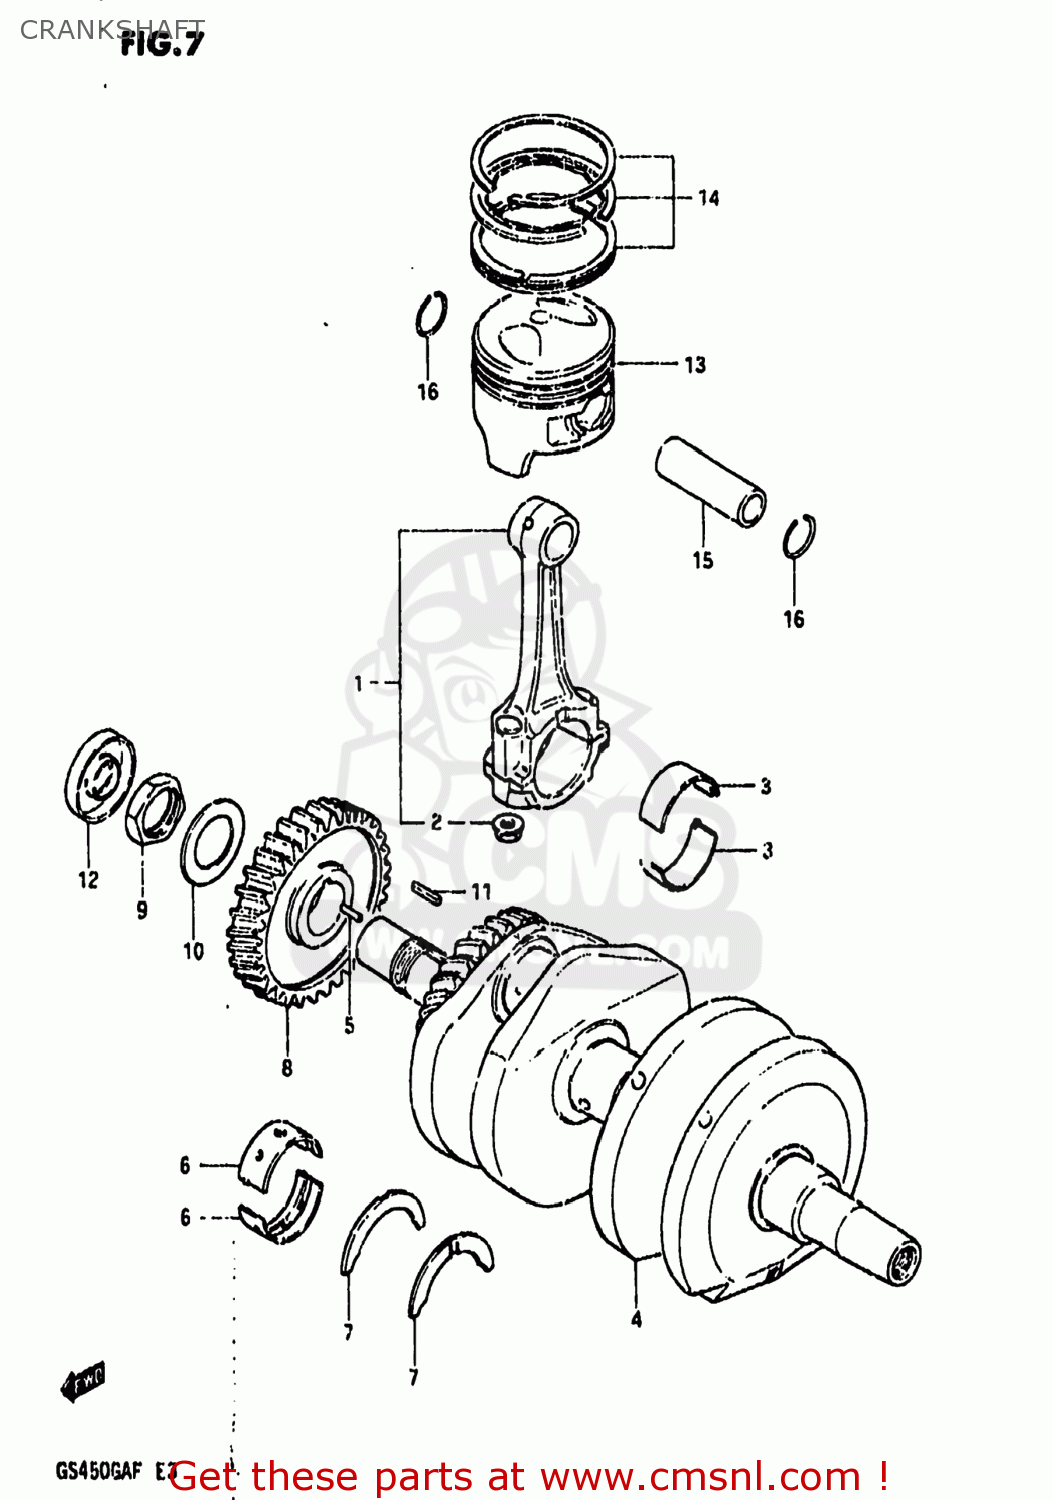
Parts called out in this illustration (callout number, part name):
1	ROD ASSEMBLY,CONNECTING
2	NUT
3	BEARING,CRANK PIN
4	CRANKSHAFT
5	PIN 3X5
6	METAL CRANKSHAFT
7	PLATE,CRANK THRUST
8	GEAR,PRIMARY DRIVE
9	NUT
10	WASHER
11	KEY
12	SEAL,OIL(22X40X8)
13	PISTON
14	RING SET,PISTON
15	PIN,PISTON (18MM)
16	CIRCLIP
